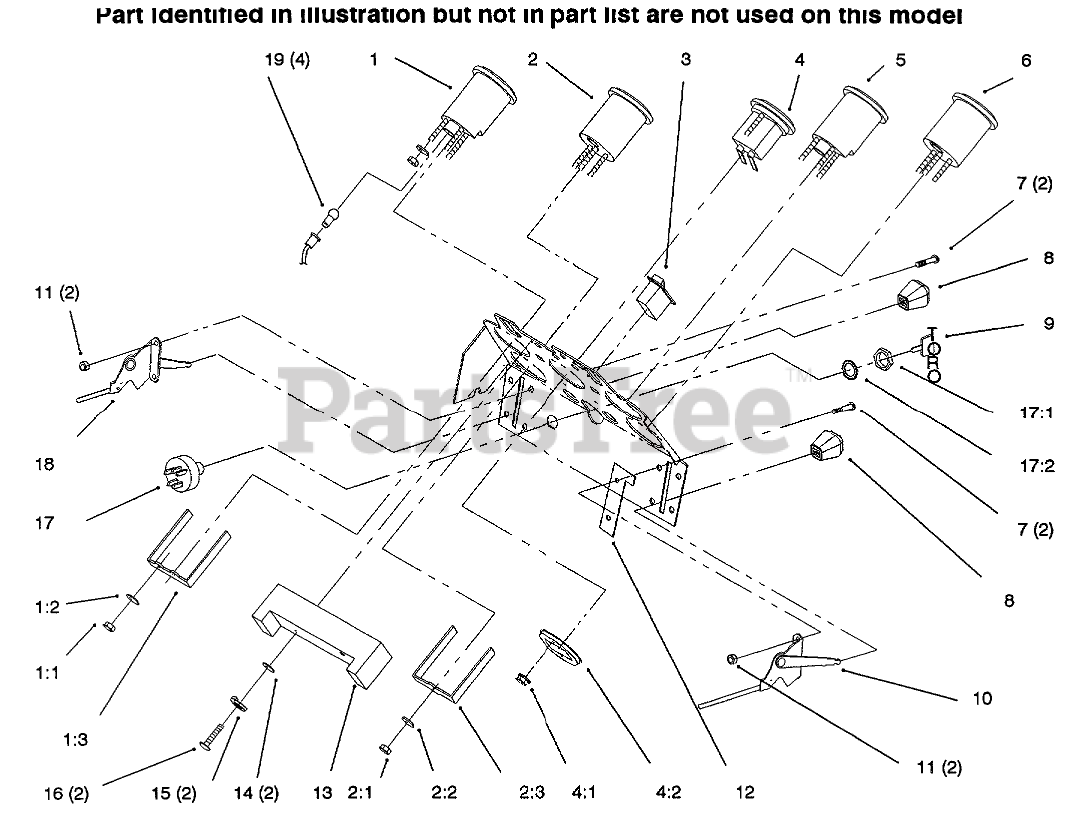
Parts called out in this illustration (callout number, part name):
1	TACHOMETER
2	FUEL-GAUGE
3	SWITCH-HEADLIGHT
4	Hourmeter
5	VACUUM-GAGE
6	Voltmeter
7	SCRW-PHC
9	KEY-IGNITION
10	CONTROL-CHOKE
11	Nut
12	STOP-CHOKE
13	CIRCUIT-BRD 8 LIGHT
14	WASHER-FLAT
15	WASHER-LOCK
16	Screw
17	IGNITION SWITCH ASM
18	CONTROL-THROTTLE
19	LAMP-MINIATURE GE 53X
